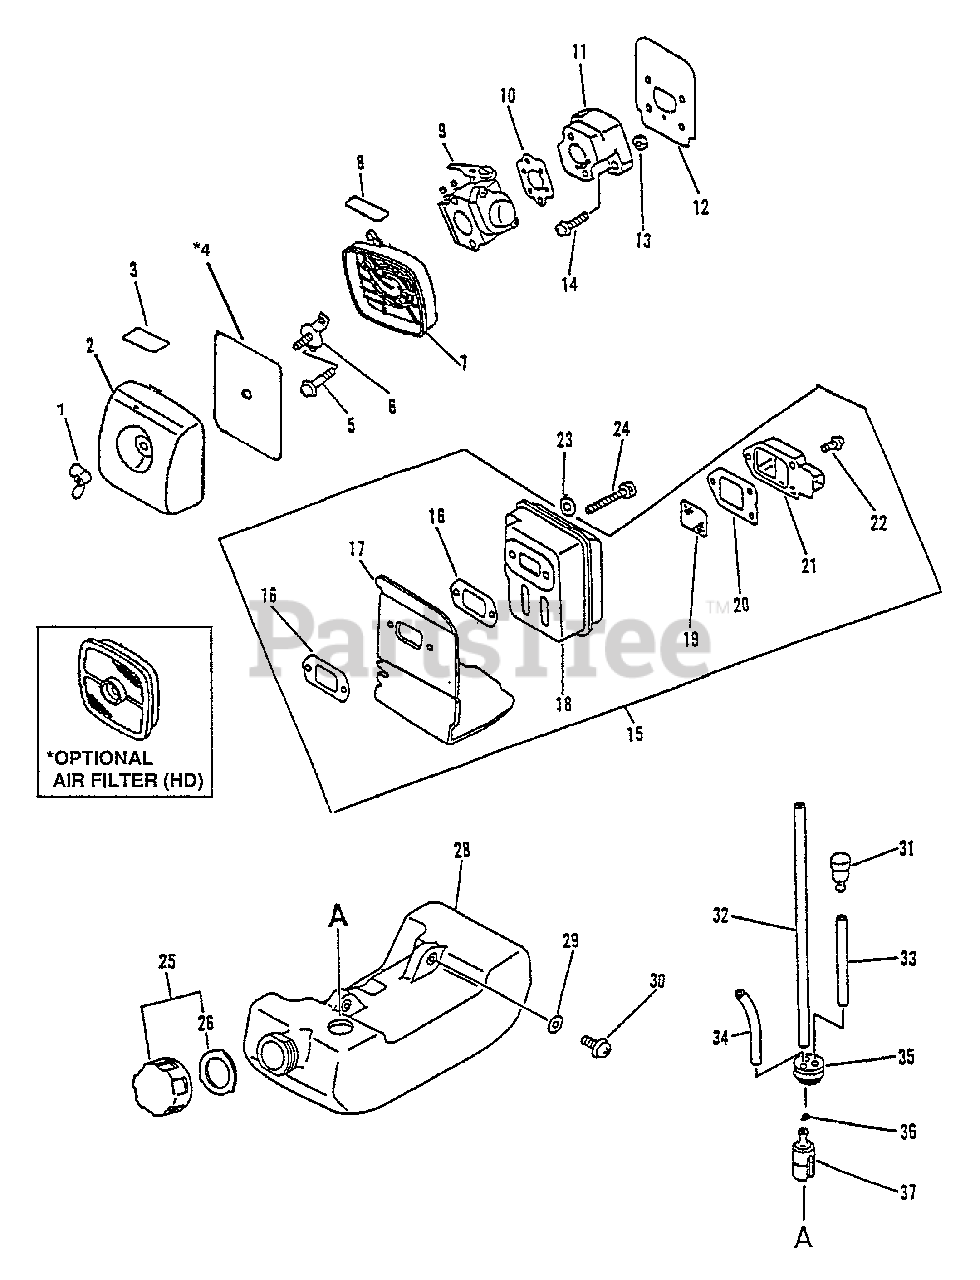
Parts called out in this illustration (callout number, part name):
1	WINGNUT - 6
2	COVER, AIR FILTER
3	LABEL - TOP
4	FILTER, AIR
5	SCREW - 5X64
6	PLATE, PREVENT
7	AIR FILTER CASE ASSY
8	LABEL - CHOKE
9	CARBURETOR C1U-K29
10	GASKET, INTAKE
11	INSULATOR, INTAKE
12	SHIELD, INTAKE
14	SCREW - 5X20
15	MUFFLER ASSY
16	GASKET, EXHAUST
17	COVER, EXHAUST
19	SCREEN, SPARK ARRESTOR
20	GASKET, EXHAUST
21	GUIDE, EXHAUST - OUTER
22	SCREW - 4X10
23	WASHER - 5
24	SCREW - 5X55
25	CAP ASSY
26	GASKET, CAP
28	TANK, FUEL
29	WASHER - 5
30	SCREW - 5X16
31	VENT, FUEL TANK
32	PIPE - 3X5X180 -- BLACK
33	PIPE - 3X5X70 -- BLACK
34	PIPE - 3X6X80 -- CLEAR
35	GROMMET
36	CLIP - 6
37	FILTER, FUEL
